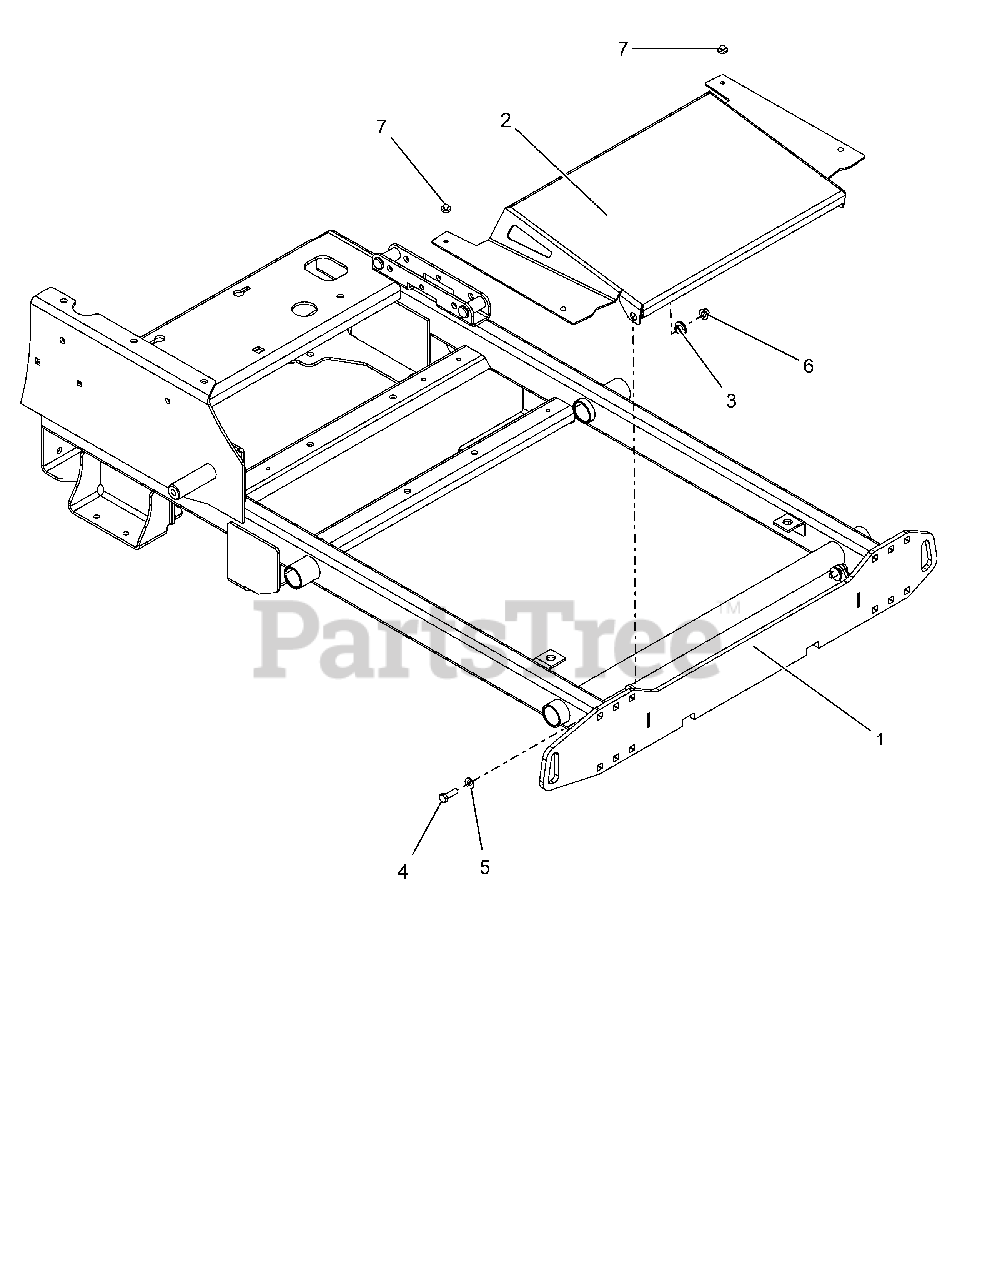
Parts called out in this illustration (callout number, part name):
1	WMT,FRAME,48-52" PRO-STANCE
2	SHEILD, FRONT PRO-STANCE
3	BSHG-FLG .32X.500X.344X.880
4	@BLT-HEX .31-18X1.00 GR5 YWZC
5	@WSHR-FL-STL.344X.688X.065YWZC
6	@NUT-LK-TOP-FLG .31-18 YWZC
7	BUMPER GROMMET
